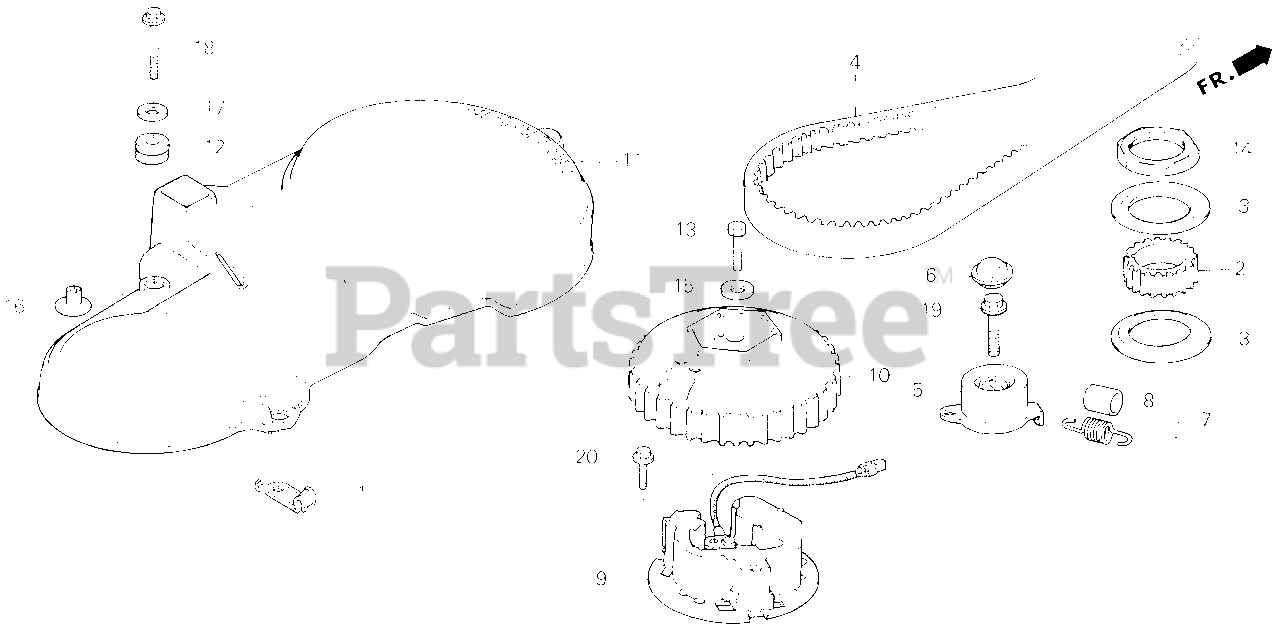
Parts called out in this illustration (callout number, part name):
1	CLAMP, TUBE
2	PULLEY, TIMING
3	PLATE, TIMING BELT GUIDE
4	BELT, TIMING
5	TENSIONER, TIMING BELT
6	CAP, TIMING BELT TENSIONER
7	SPRING, TIMING BELT ADJUSTING
8	BOOT, SPRING
9	COIL ASSY., PULSER
10	ROTOR, PULSER
11	COVER, FLYWHEEL
12	GROMMET, CASE (LOWER)
13	BOLT, FLANGE (10X32)
14	NUT, LOCK (48MM)
15	WASHER (10X28X5)
16	COLLAR, IGNITION CONTROL MODULE CASE
16	COLLAR, MODULE IGNITION CONTROL CASE (CDI)
17	WASHER, PLAIN (6MM)
18	BOLT, FLANGE (6X25)
19	BOLT, FLANGE (10X38)
20	BOLT, FLANGE (6X12)
